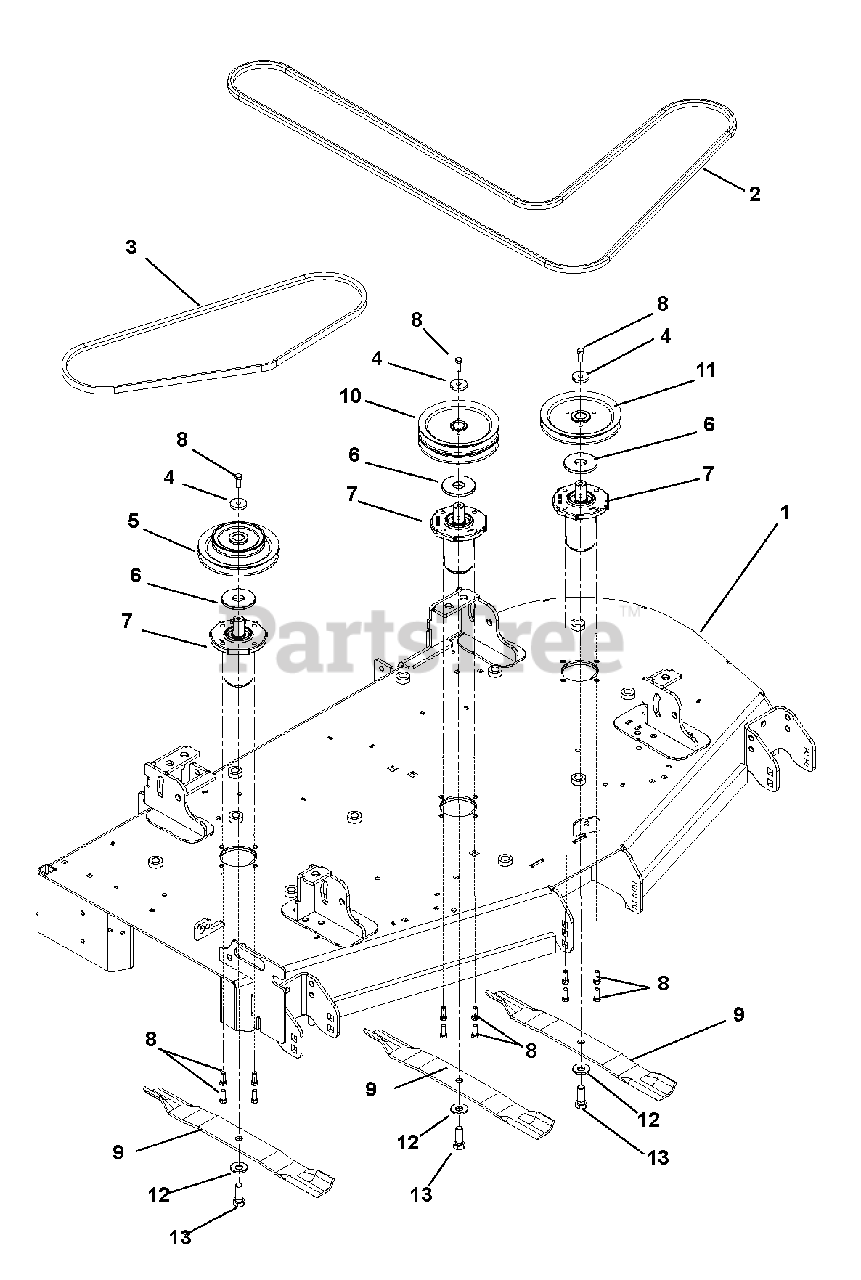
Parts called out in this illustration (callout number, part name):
1	Deck, 52"
2	Hex Belt, BB – Wrapped
3	V-Belt, B-Cogged
4	Washer, Flat Steel .406 x 1.50 x .245
5	Sheave, 1" ID x 6.00" OD and 3.50" OD
6	Retainer, Grease
7	Assembly, Spindle G3500
8	Bolt, Hex .38-16 x 1.00
9	Blade, Mulch 18.00"
10	Pulley, Double
11	Pulley, Single 1"ID x 6.00" OD
12	Washer, Bellville .63 x 1.625 x .14
13	Bolt, Hex .62-18 x 1.75 Grade 8
